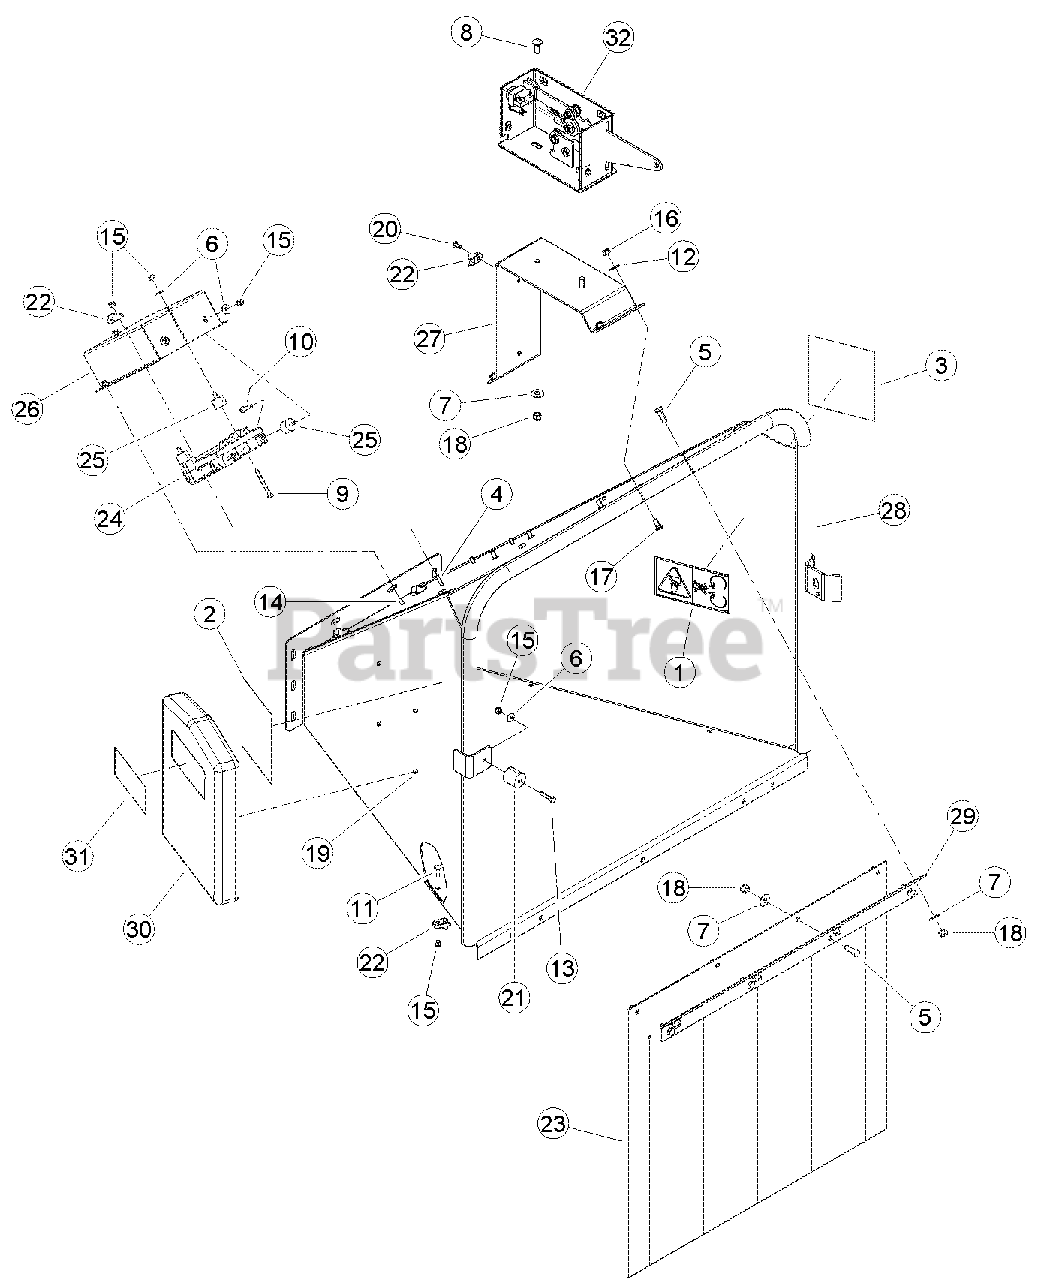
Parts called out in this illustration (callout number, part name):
1	DECAL, BLADE DANGER ISO
2	DECAL, FEED POSITION
3	DECAL, FEED POSITION
4	BOLT, 1/4 X 1 HEX HD GR5 ZP
5	BOLT, 3/8 X 1 HEX HD GR5 ZP
6	WASHER, 1/4 FLAT ZP
7	WASHER, 3/8 FLAT ZP
8	BOLT, 3/8 X 1 CRG GR5 NC ZP
9	BOLT, 1/4 X 2-1/4 HEX HD GR5 ZP
10	BOLT, 1/4 X 1-1/4 HEX HD GR5 ZP
11	BOLT, 1/4 X 1 CRG GR5 NC ZP
12	WASHER, 5/16 FLAT ZP
13	BOLT, 1/4 X 1 HEX GR8 ZP
14	BOLT, 1/4 X 5/8 HEX HD GR5 ZP
15	NUT, 1/4 NE NYLOCK ZP
16	NUT, 5/16 NE NYLOCK ZP
17	BOLT, 5/16 X 3/4 CRG GR5 NC ZP
18	NUT, 3/8 NE NYLOCK ZP
19	RIVET, AL BLIND 1/4 X 1/2 DOME HEAD
20	RIVET, AL BLIND 1/4 X 3/4 DOME HEAD
21	BUMPER, RECESSED RUBBER
22	CLAMP, CABLE MOUNT
23	FLAP, CHUTE
24	CONTROLLER, PLUS 1 CHIPPER
25	BUMPER, 1" OD W/1/4" STUD
26	ENCLOSURE, PLUS 1 MOUNT
27	MOUNT, SWITCH BOX
28	WELDMENT, CHIPPER CHUTE
29	SUPPORT, CHIPPER FLAP
30	ASSEMBLY, MANUAL CONTAINER, SERVICE PART
31	DECAL, MUTILINGUAL MANUAL
32	ASSEMBLY, SWITCH BOX
